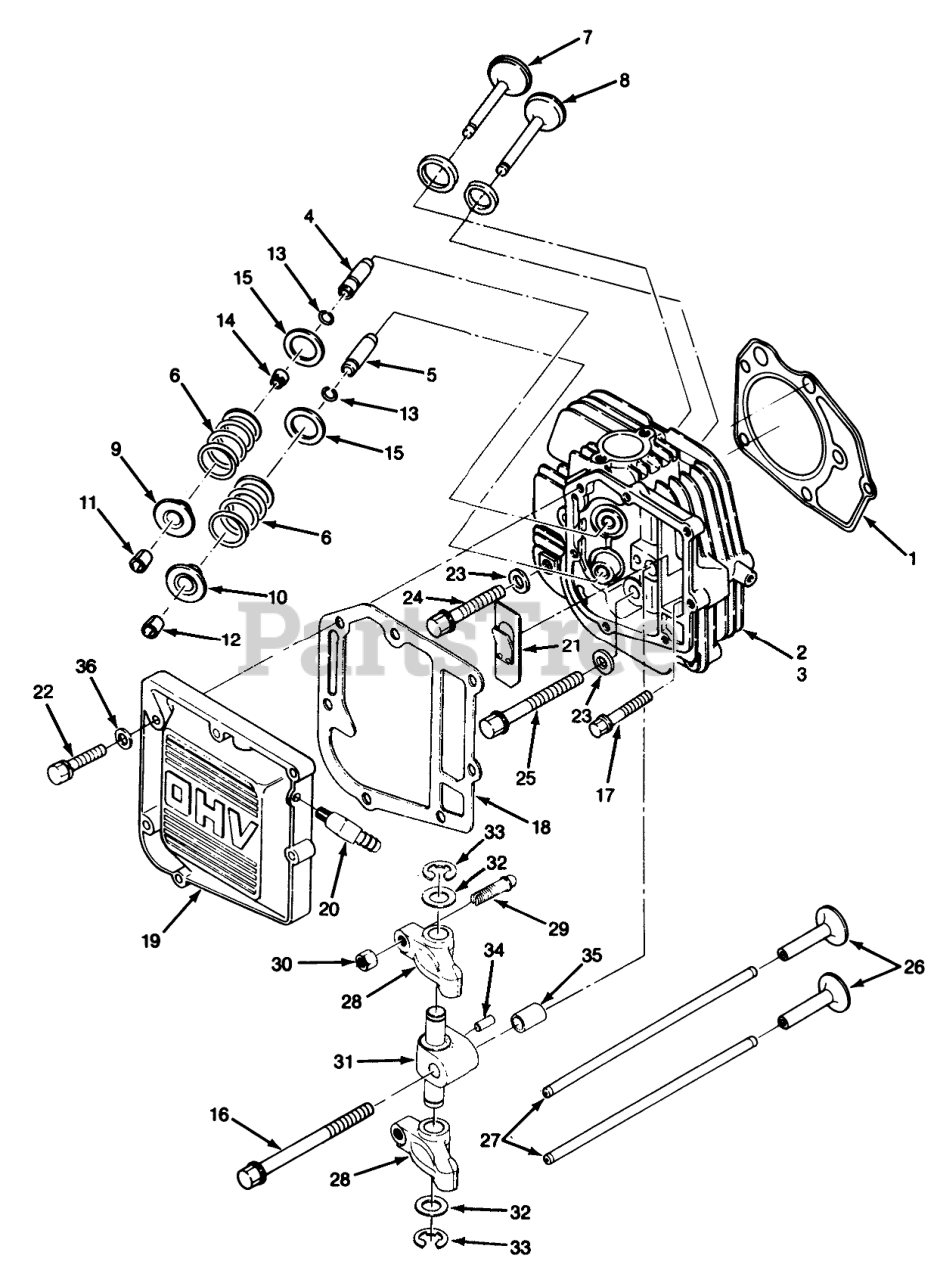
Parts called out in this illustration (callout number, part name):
1	GSKT-CYL HEAD
2	Cylinder Head Assembly (Incl. Ref. #4-15)
3	Cylinder Head Assembly (Incl. Ref. #4-5)
4	GUIDE-VALVE INTAKE
5	GUIDE-VALVE EXHAUST
6	SPRING-VALVE
7	VALVE-INTAKE MKD IN
8	VALVE-EXHAUST MKD EX
9	RETAINER-VLV SPG IN
10	RETAINER-VLV SPG EX
11	Lock-Intake
12	LOCK-VALVE EXHAUST
13	RING-VALVE GUIDE
14	Seal-Intake
15	WASHER-VALVE SPRING
16	BLT-CYL HD M10X125MM
17	BLT-CYL HD M8X50MM
18	Seal
19	Cover-Valve
20	ELBOW-90 DEGREES
21	BREATHER
22	SCRW-CP SH M6X25MM
23	WASHER-FLAT M10
24	BLT-CYL HD M10X66MM
25	BLT-CYL HD M10X66MM
26	TAPPET
27	ROD-PUSH
28	Rocker Arm Assembly (Incl. Ref. #29-30)
29	SCRW-LASH ADJUSTING
30	NUT-LASH ADJUSTING
31	SHAFT-ROCKER ARM
32	Rocker Arm Washer
33	CLIP-RETAINER
34	PIN-DOWEL
35	PIN-DOWEL HOLLOW
36	Washer
